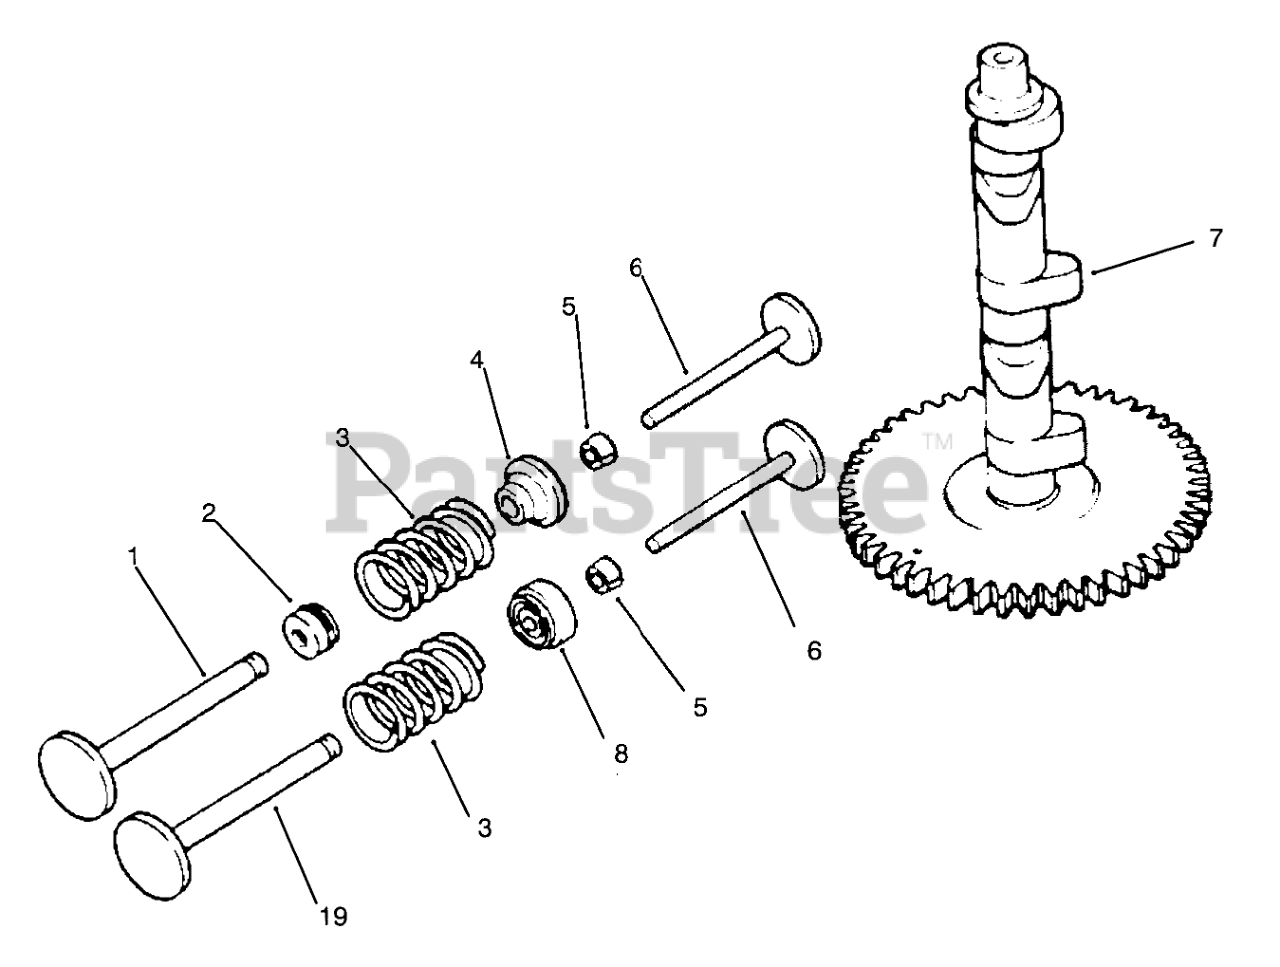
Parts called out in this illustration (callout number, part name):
1	Valve-Intake
2	Seal-Valve Stem
3	Spring-Valve
4	Retainer-Spring
5	Kit-Retainer
6	Tappet
7	Camshaft
8	Rotator
9	Valve-Exhaust
